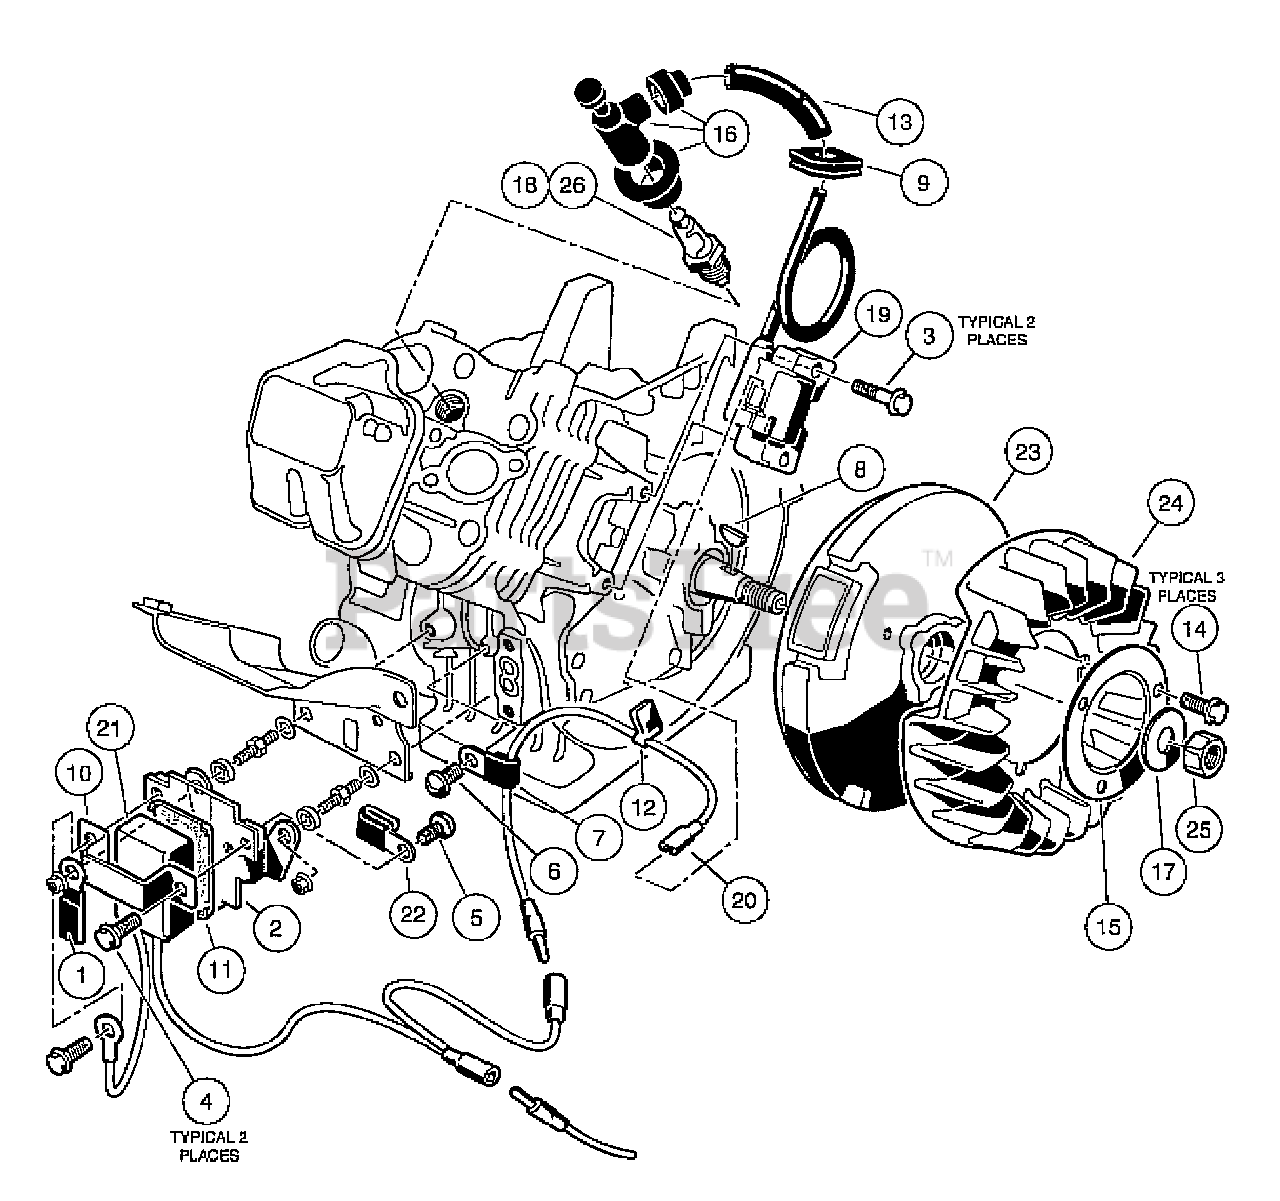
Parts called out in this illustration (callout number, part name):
1	Clamp
2	Bracket, RPM Limiter
3	Bolt, Flange Head
4	Bolt, Flange Head, M6 x 1 x 12 mm
5	Screw, Pan WP Cross
10	Band, RPM Limiter Mount
11	Damper, RPM Limiter
13	Tube, 7mm X 10mm X 70mm
14	Bolt, Flanged
15	Plate, Flywheel Fan
16	Cap Asm Plug
17	Washer, Flat
18	Spark Plug, OHV (Autolite)
19	Coil, Ignition
20	Lead Wire Assy
21	Limiter, RPM
22	Clamp, Steel
25	Nut, Hex, 18 mm Fine
26	Spark Plug, OHV (NGK)
